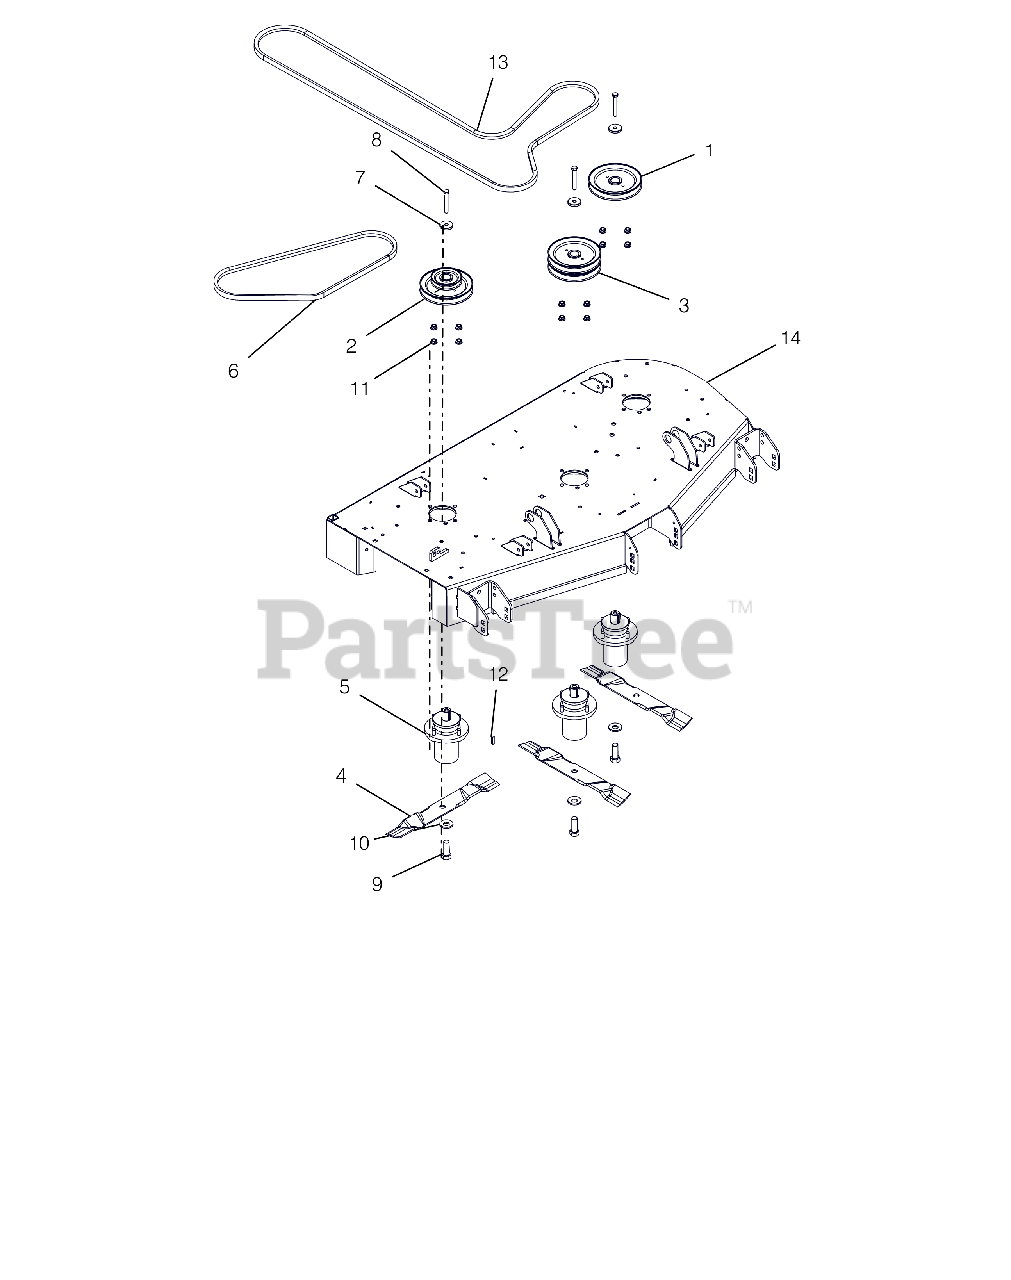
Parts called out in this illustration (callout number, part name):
1	PULLEY, SINGLE-1"ID X 6" OD
2	PULLEY, DOUBLE-1"IDX3.50"&6.0
3	PULLEY, DOUBLE
4	BLADE, MULCH 16.25
5	ASM, MAINT FREE SPINDLE ALUM
6	V-BELT, B-COGGED
7	RETAINER, SHEAVE
8	BLT-HEX .38-16X2.75 GR8 YWZC
9	BLT-HEX .62-18X1.75 GR8 YWZC
10	WSHR-BLVL .669X1.535X.138
11	NUT-LK-CTR-FLG .38-16 YWZC
12	KEY, SQ .25X.25X1.00 RC 40-50
13	V-BELT, HB SECTION
14	WLDMT, 48" SIDE DISCH DECK -CE
